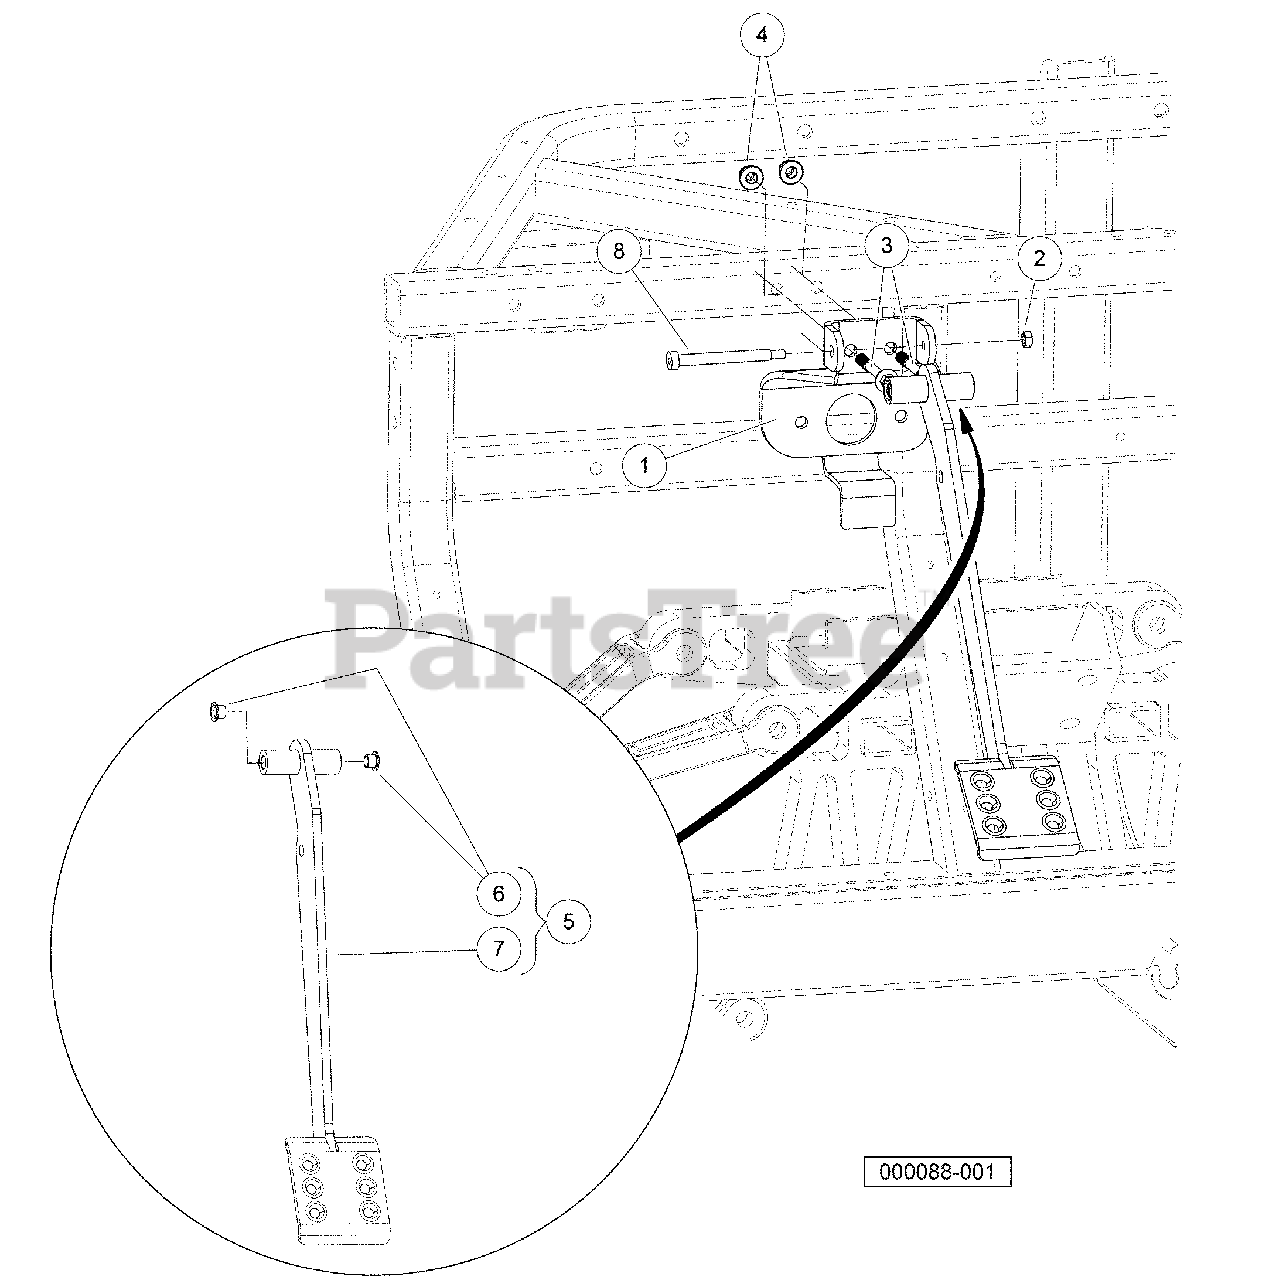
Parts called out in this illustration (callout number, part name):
1	Bracket, Pedal, Brake
2	Nut M6x1 Mech Def Center
3	Bolt Flanged Head, M8 X 1.25 X 65
4	Lock Nut, Flg M8 X 1.25 Nylon
5	Asm, Pedal, Brake, Hung
6	Bushing, Greaseless
7	Weldment, Pedal, Brake, Hung
8	Bolt, Shoulder, M8 X 70, Hc
